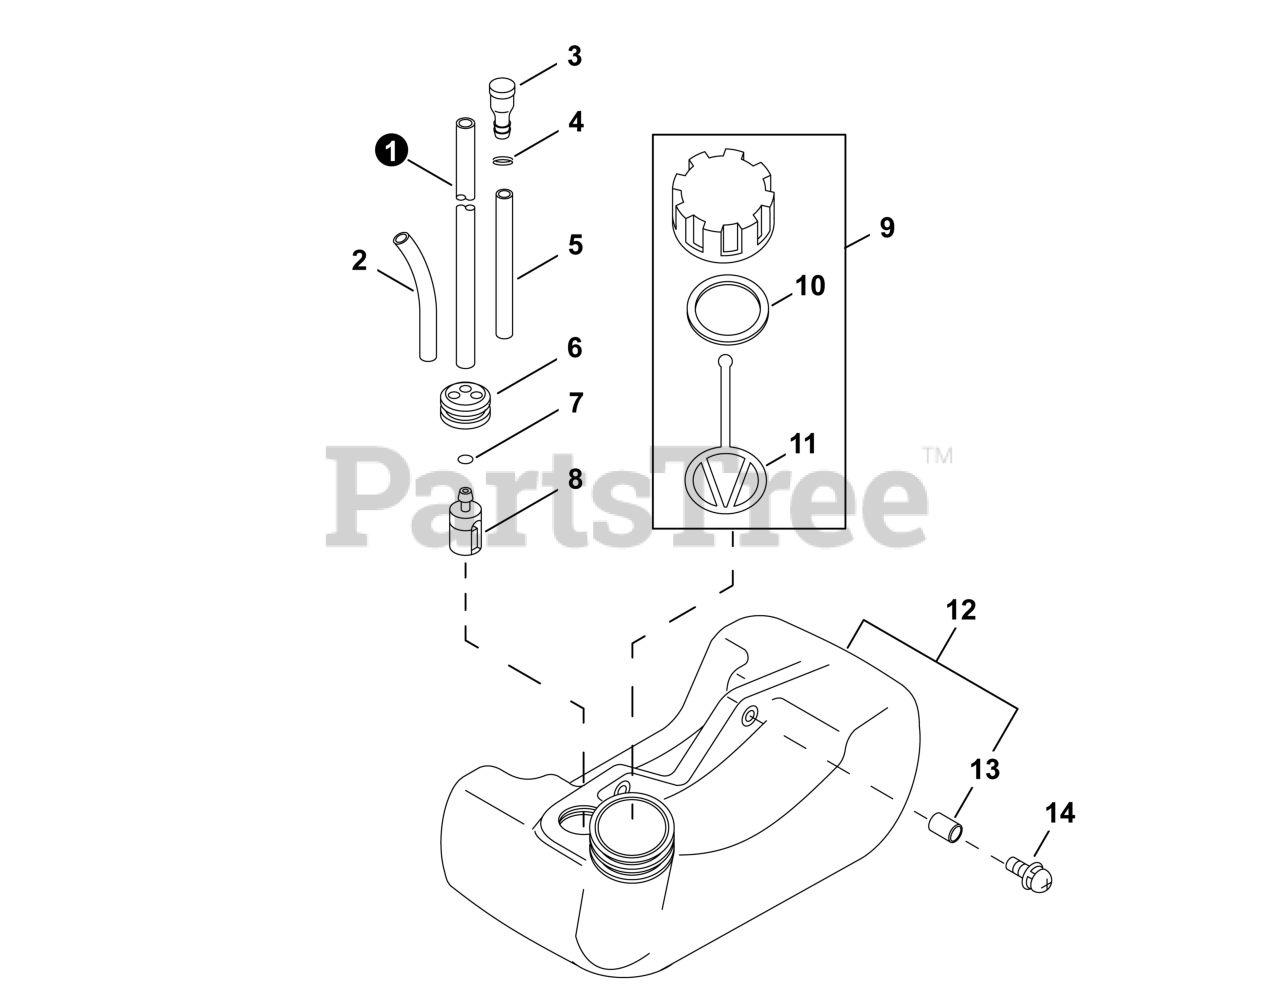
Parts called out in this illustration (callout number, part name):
1	PIPE, FUEL 3x5x180 BLACK
2	PIPE, FUEL RETURN 3x6x70
3	VENT ASSY
4	CLIP 5.5
5	PIPE, FUEL 3x5x70 BLACK
6	GROMMET, FUEL 5
8	FILTER, FUEL
9	CAP ASSY, FUEL
10	GASKET, FUEL CAP
11	CONNECTOR, CAP L= 123
12	TANK, FUEL
13	SPACER 6.2x7.8x6
14	SCREW 5x16
